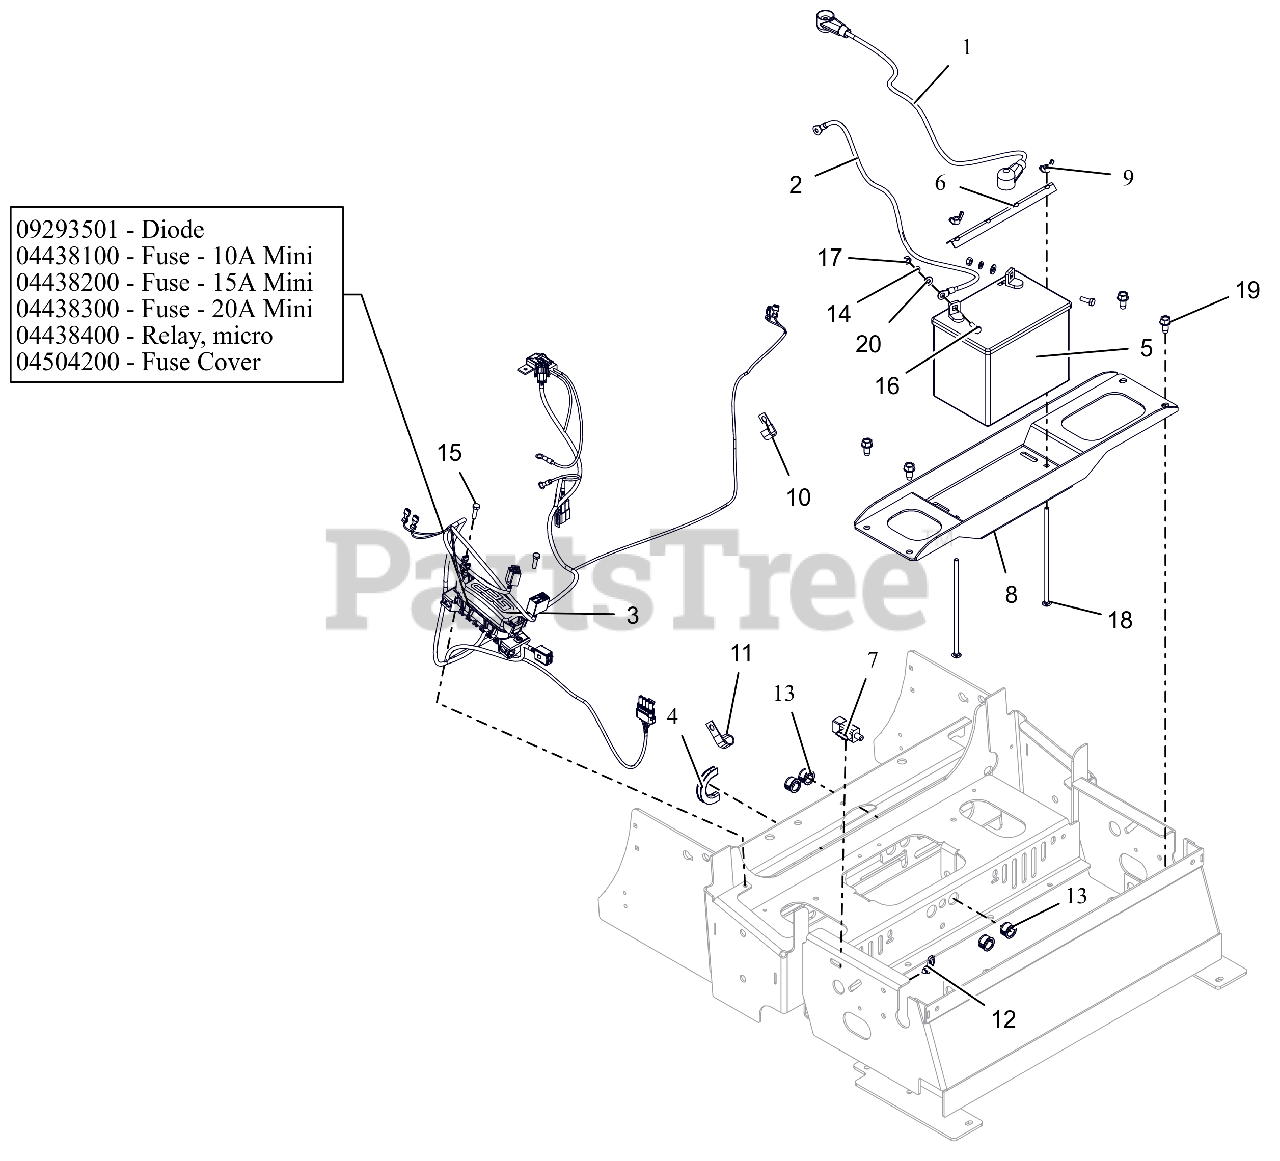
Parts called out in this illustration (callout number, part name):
1	CABLE - POS BATT W/BOOTS 6X35
2	CABLE-NEGATIVE BATTERY 35.00"
3	HRNSS,PT200/400 NON-EFI WIRING
3	DIODE, CONNECTOR SHELL
3	FUSE,10 AMP MINI-ATC
3	FUSE,15 AMP MINI-ATC
3	FUSE,20 AMP MINI ATC
3	RELAY,MICRO5 TERML W/RESISTOR
3	COVER, HARNESS FUSE/RELAY MOD
4	STRIP, COWL
5	BATTERY, 300 CCA 10U1L
6	HOLD DOWN
7	SWITCH, SNAP IN - N.O./N.O.
8	PT200/400 BATTERY TRAY - RED
9	NUT, LK-WING .25-20 ZCC
12	CABLE TIE W/ TREE (.25 HOLE)
13	BUSH, PANEL SNAP .687X.875X.56
14	WSHR,LK-REG .250X.062 ZCC
15	BLT, HEX M6-1.0 X 25 G8.8 ZCC
16	BLT, HEX .25-20X.75 G5 ZCC
17	NUT-STD .250-20 G2 ZCC
18	BTL,RHSN .250-20 X 7.5 G5 ZCC
19	SCR,TAP .375-16X.75 HWH TR ZCC
20	WSHR,FLT .281X.625X.065 ZCC
